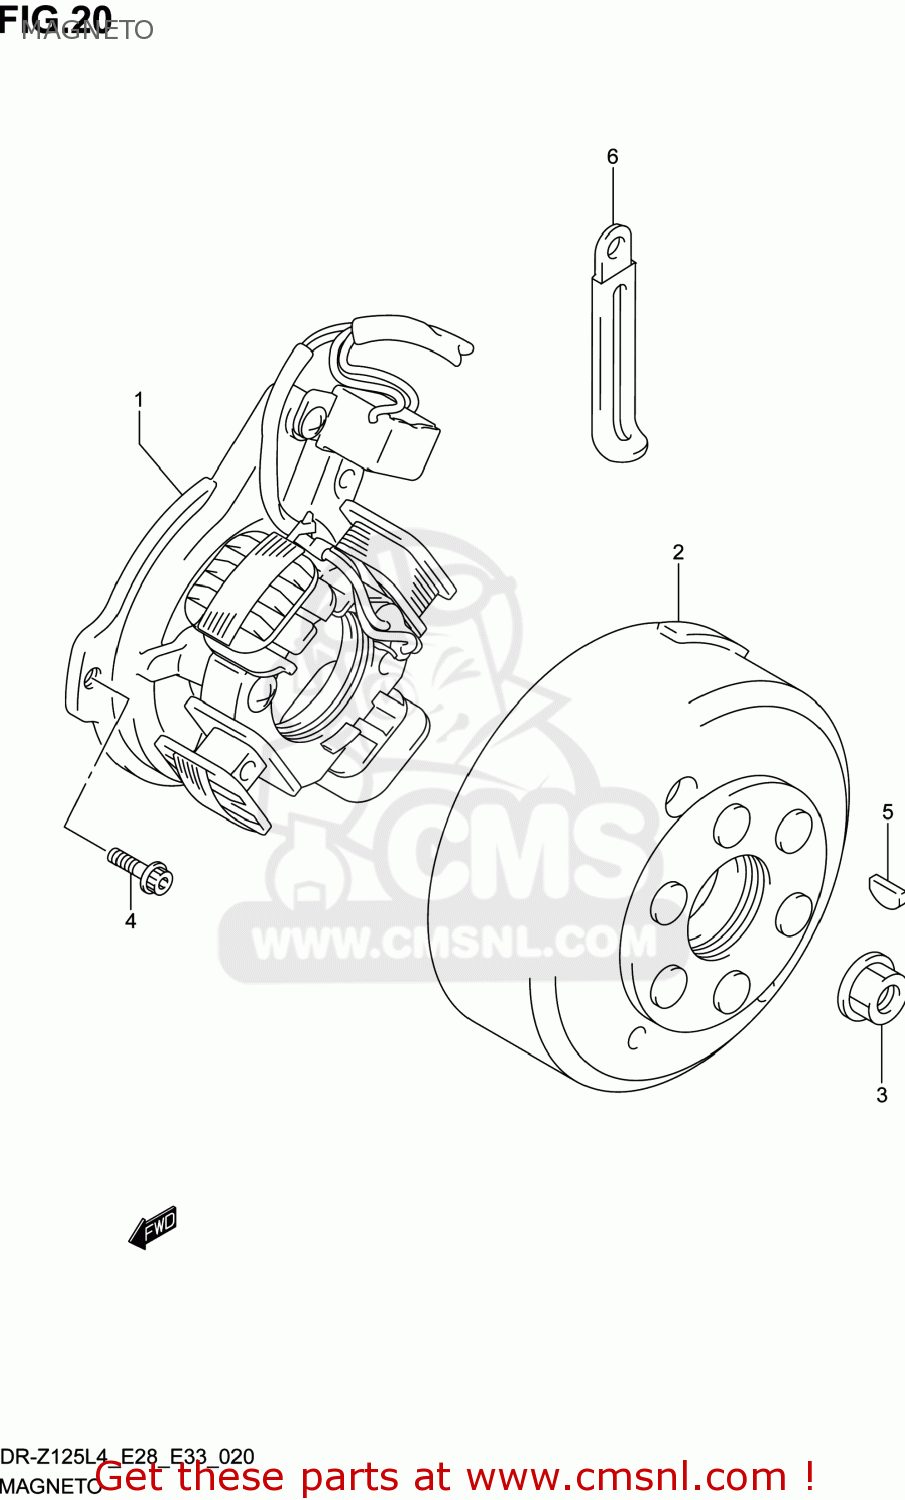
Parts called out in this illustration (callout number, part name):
1	STARTER ASSY
2	ROTOR ASSY
3	NUT
4	BOLT
5	KEY
6	CLAMP(L:80)
